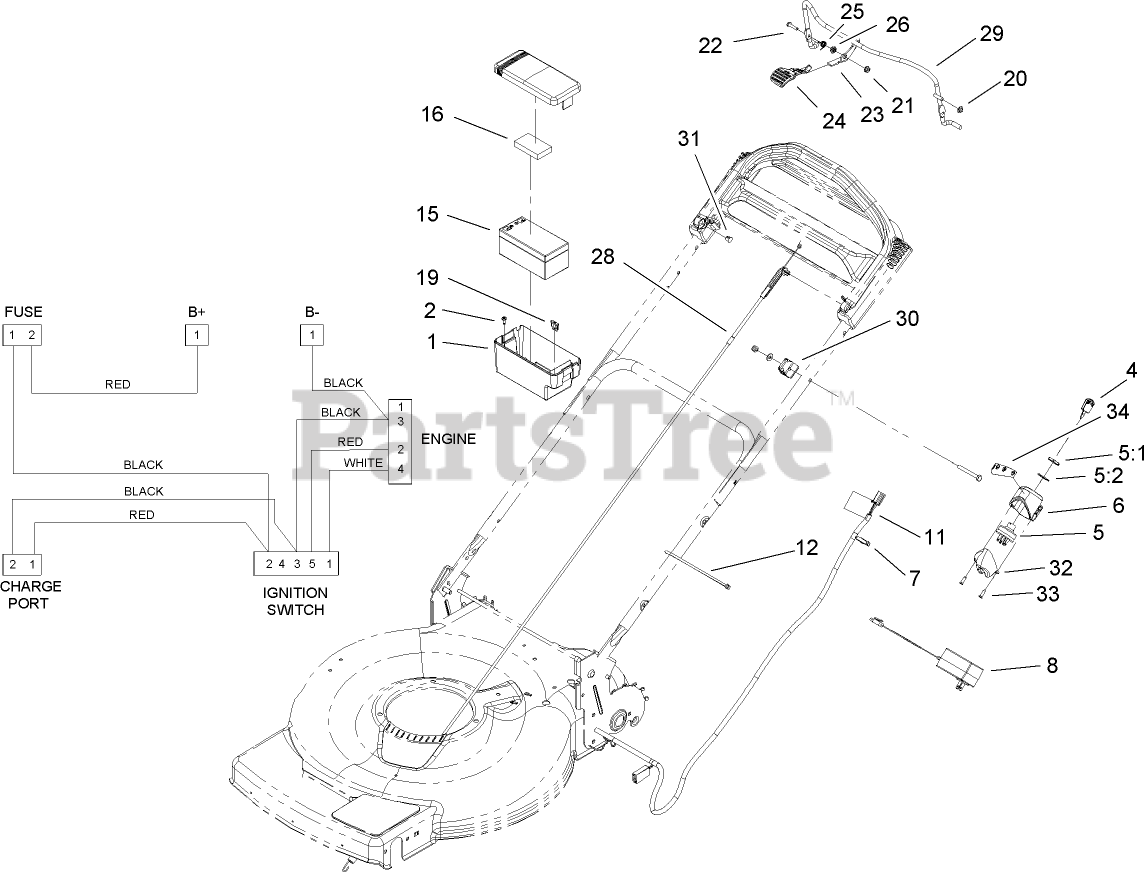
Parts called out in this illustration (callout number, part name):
1	BATTERY BOX ASM
2	SCREW-FORMING, THREAD
5	SWITCH-STARTER
5:1	NUT-HH
5:2	WASHER-LOCK
6	HOUSING-SWITCH, KEY
7	HARNESS-WIRE
8	CHARGER-BATTERY, 12 VOLT
11	DECAL-WARNING
12	TIE-CABLE
15	BATTERY-WET
16	FOAM-BATTERY, TOP
19	FUSE-40 AMP
20	NUT-SPEED
21	NUT-LOCK, FLANGE
22	SCREW-HWH
23	LEVER
25	SPRING-TORSION
26	SPACER
28	CABLE ASM
30	ANCHOR-CABLE, UPPER
31	PLUG-DOME
32	COVER-SWTCH
33	SCREW-PPH
34	DECAL-SWITCH, IGNITION
